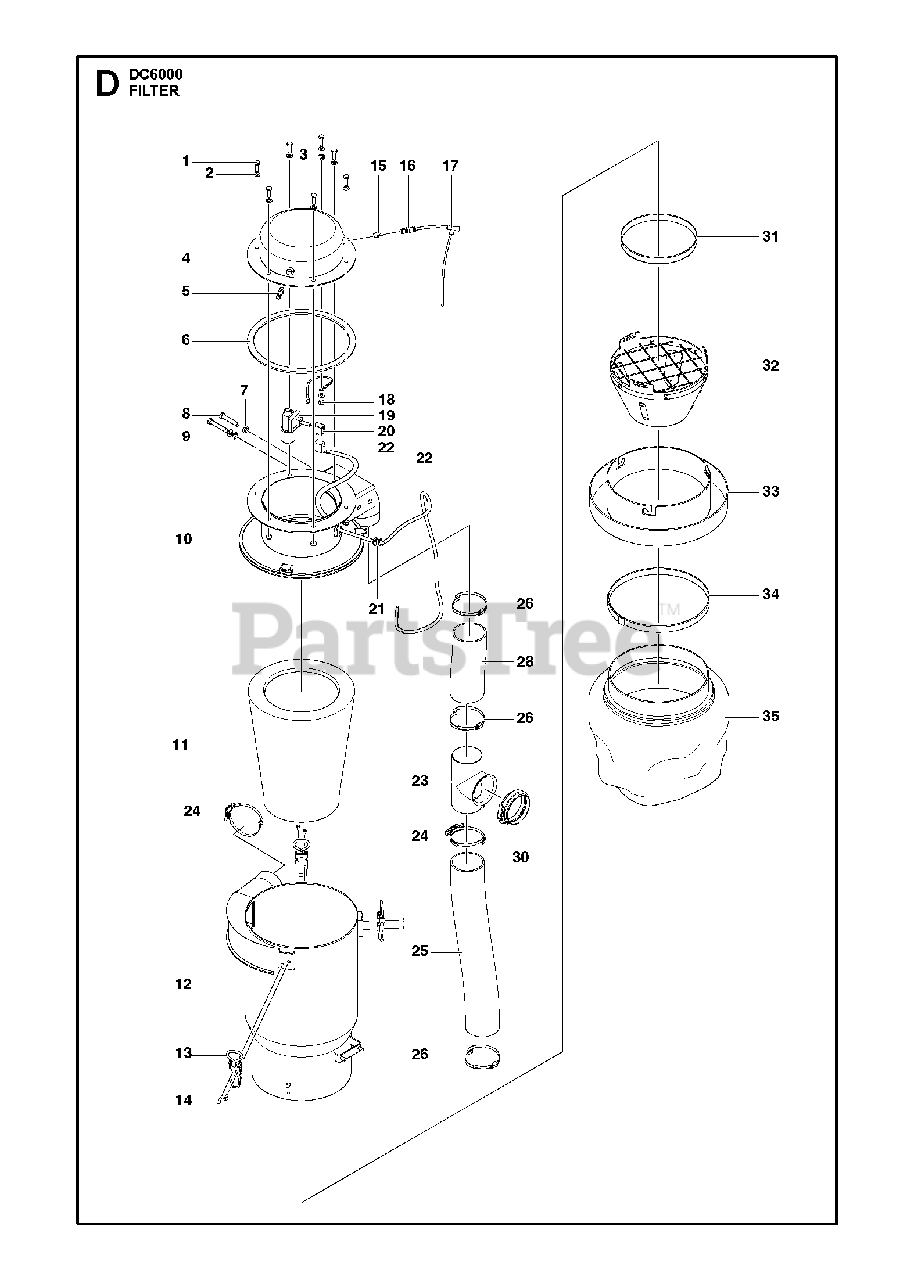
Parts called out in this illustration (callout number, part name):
2	WASHER
3	HEXAGON LOCKING NUT
7	WASHER
18	HEXAGON LOCKING NUT
